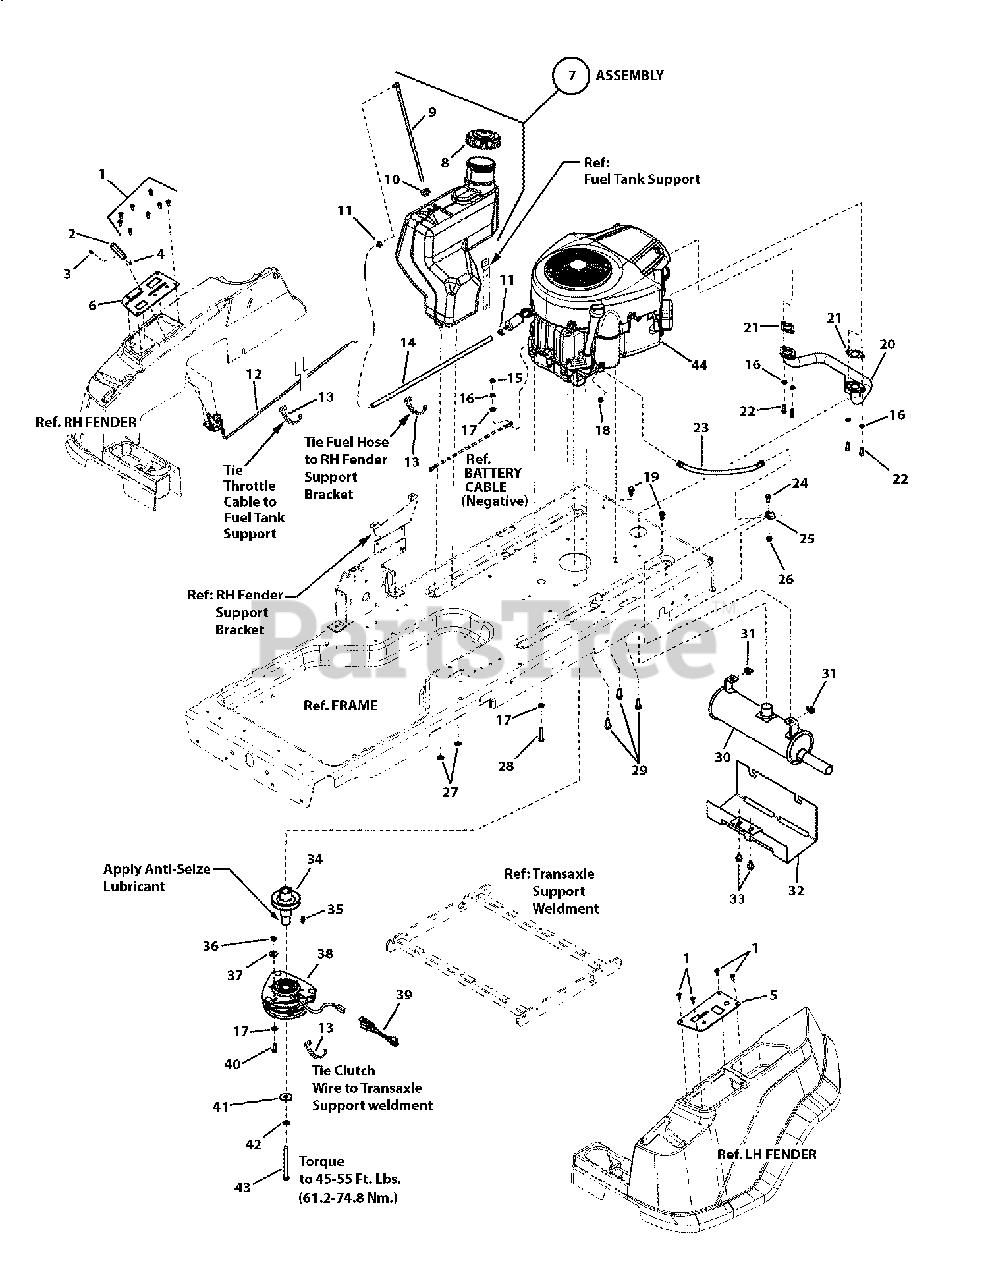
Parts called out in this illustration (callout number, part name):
1	SCREW, 1/4-20 x 5/8" Pan Head Self-Tap (Torx)
2	KNOB, Throttle, Red
3	SCREW, #8-32 x 3/8" Cross Recess Filister Head, GR 2
4	NUT, #8-32 Hex, GR 2B
5	PANEL, Control, LH
6	PANEL, Control, RH
7	ASSEMBLY, Fuel Tank, 3 Gallon (incl. 4 items shown below)
8	CAP, Fuel Tank
9	ASSEMBLY, Elbow, Pickup Tube
10	BUSHING, Fuel
11	CLAMP, Fuel Hose
12	ASSEMBLY, Throttle, Choke-A-Matic, B&S V-Twin
12	ASSEMBLY, Throttle, B&S V-Twin w/EFM
13	CABLE TIE, 7"
14	HOSE, Fuel, 1/4" x 32"
15	NUT, 5/16-18 Hex, GR 5 or B, YZ
16	WASHER, 5/16" Split Lock
17	WASHER, 5/16" Flat
18	NUT, 1/4-20 Hex Flange Lock, GR 5, YZ
19	SCREW, 5/16-18 x 3/4" Hex Flange Lock, Black
20	MANIFOLD, B&S V-Twin
21	GASKET, Exhaust B&S Reg (No Chre) 273485
22	SCREW, 5/16-18 x 3/4" Allen Socket Head, GR 8 Black
23	HOSE, Oil Drain
24	SCREW, 5/16-18 x 3/4" Hex Head Cap, GR 5, YZ
25	HARNESS CLIP, 5/8"
26	NUT, 5/16-18 Flange Lock, YZ
27	RETAINER, 3/8" Bolt
28	SCREW, 5/16-18 x 1-3/4" Hex Head Cap, GR 5 YZ
29	SCREW, 3/8-16 x 1" Hex Washer Self-Tap
30	MUFFLER, RZT
31	SPEEDNUT, 5/16 -18, Lug Type .025/.150 B
32	HEAT SHIELD, Muffler
33	SCREW, 3/8-16 x 5/8" Hex Washer Self-Tap
34	ASSEMBLY, Engine Pulley
35	KEY, 1/4" Square x 3/4"
36	NUT, 5/16-18 Hex Center Lock, YZ
37	FENDER WASHER, 5/16"
38	CLUTCH, Ogura JD-11
39	HARNESS, Jumper (used with Ogura Clutch only)
40	SCREW, 5/16-18 x 7/8" Hex Head Cap, GR 5, YZ
41	WASHER, .468 ID x 1-1/2" OD x .188 Flat, YZ
42	WASHER, 7/16" Split Lock, YZ
43	SCREW, 7/16-20 x 4-1/2" Hex Head Cap, GR 5
44	* ENGINE, 26 HP, B&S V-Twin (early models)
44	* ENGINE, 26 HP, B&S V-Twin
44	* ENGINE, 27 HP, B&S Pro w/EFM (early models)
44	* ENGINE, 27 HP, B&S Pro w/EFM
